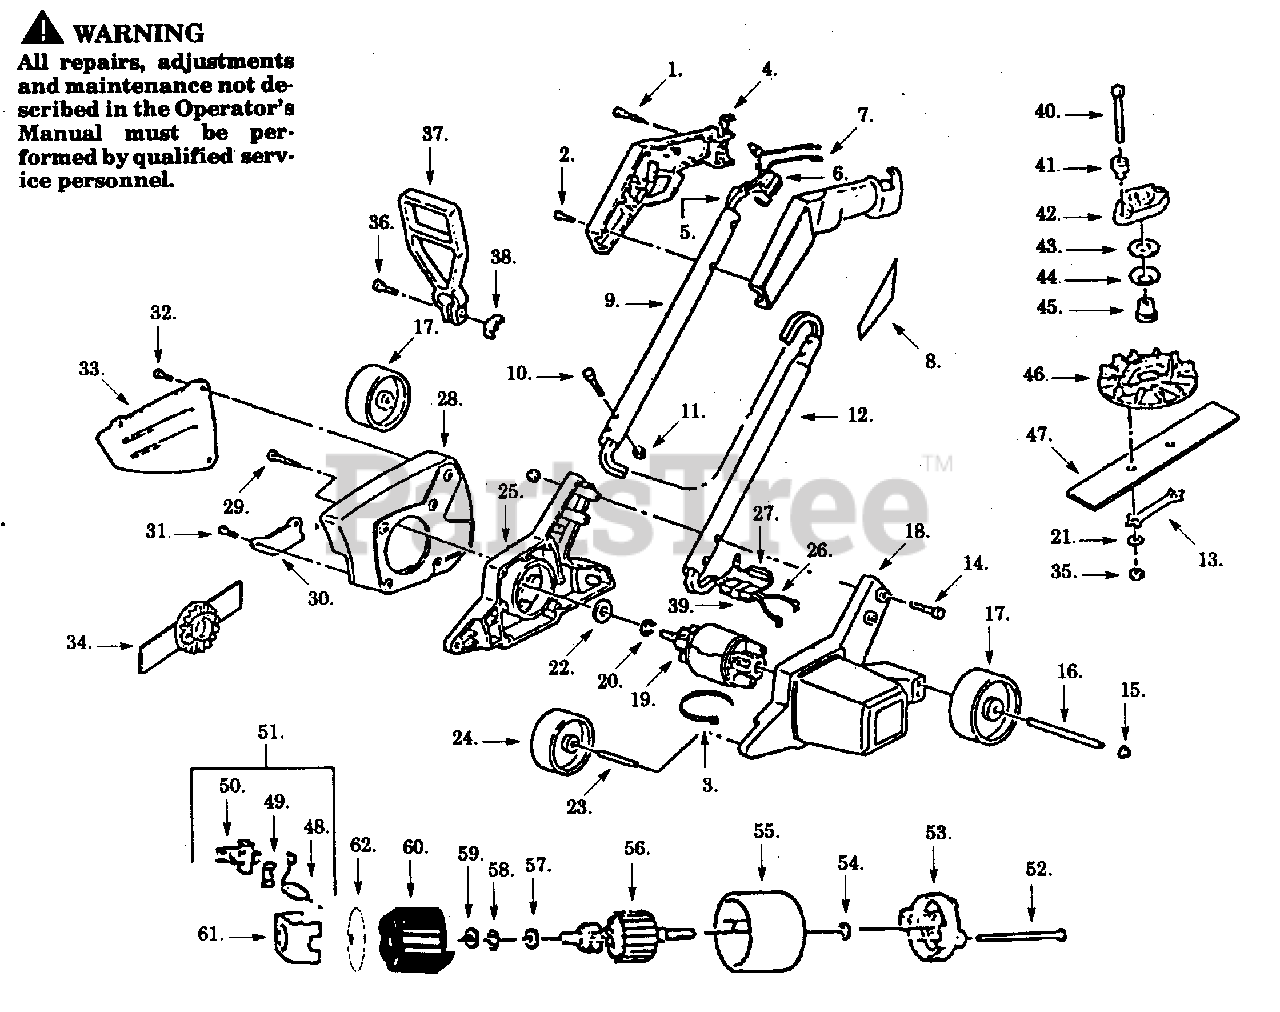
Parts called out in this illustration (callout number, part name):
3	Tie Strap
4	Handle Set
5	Harness Ass'y.
6	Trigger Switch
7	Power Plug
8	Warning Label
9	Upper Tube
12	Lower Tube
13	Lock Strap
16	Rear Axle
17	Rear Wheel
18	Motor Cover
19	Motor Ass'y.
20	Retaining Ring
21	Lockwasher
23	Front Axle
24	Front Wheel
26	P.C. Board Ass'y.
27	Resister
28	Housing Guard
30	Blade Guide
33	Blade Guard
34	Blade Ass'y.
37	Assist Handle
38	Wing Nut
41	Insulating Sleeve
42	Clutch Plate
44	Spring Washer
45	Clutch Sleeve
48	Carbon Brush
49	Spring Brush
50	Brush Holder
51	Brush Kit (Inc. 48,49,50)
53	Endbell Ass'y. (Drive)
55	Field Ass'y.
56	Armature Ass'y.
59	Retaining Ring
60	Endbell Ass'y. (Brush)
61	Insulator
62	Brush Insulator
